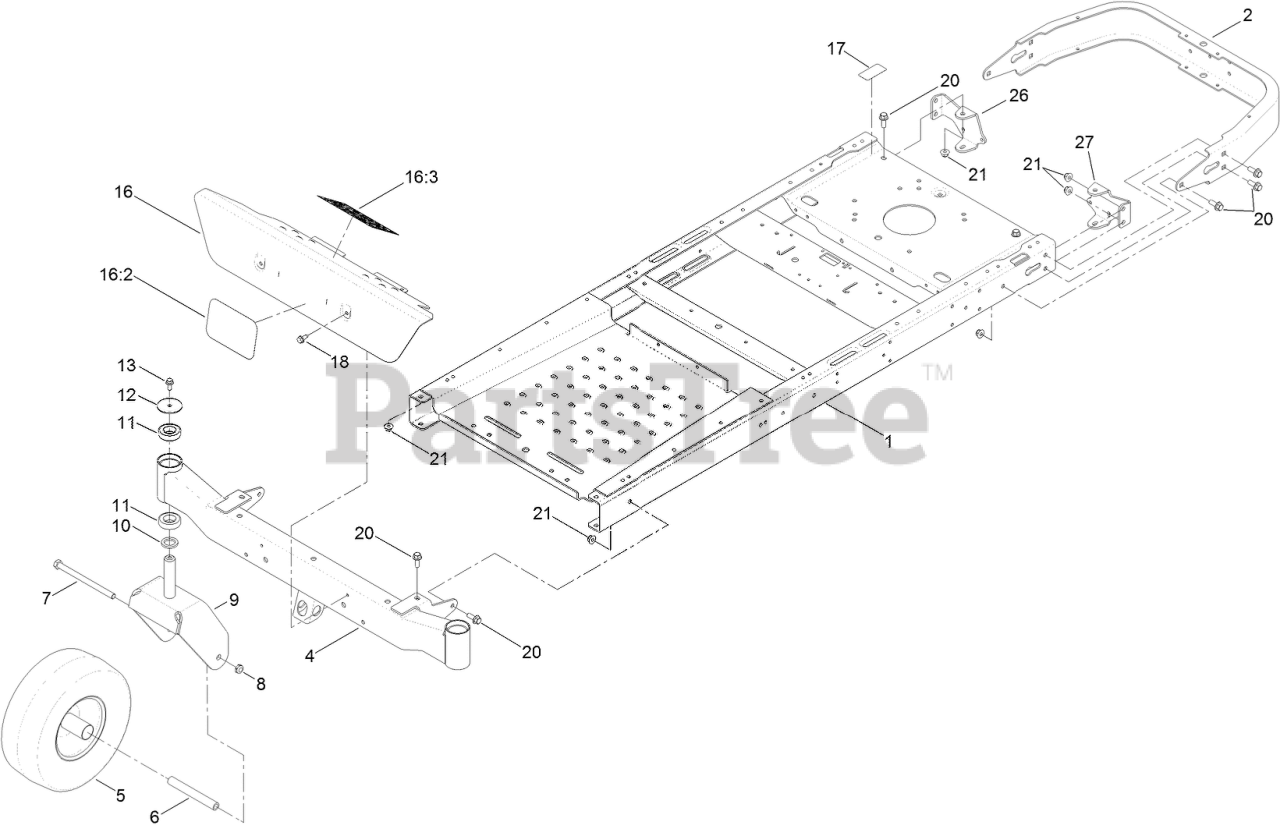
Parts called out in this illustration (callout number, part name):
2	BUMPER-REAR (WIDE)
4	AXLE-FRONT, WIDE
5	13 INCH WHEEL AND TIRE ASM
6	SPANNER
7	SCREW-HH
8	NUT-LOCK, NI
9	FORK-CASTER
10	WASHER-THRUST
11	BEARING-BALL
12	WASHER
13	SCREW-HHF
16	FOOTREST ASM
16:2	DECAL
16:3	DECAL-DANGER
17	DECAL-BYPASS
18	SCREW-HWHTF
20	SCREW-HHF
21	NUT-HF, NI
26	MOUNT-HYDRO, REAR (RH)
27	MOUNT-HYDRO, REAR (LH)
